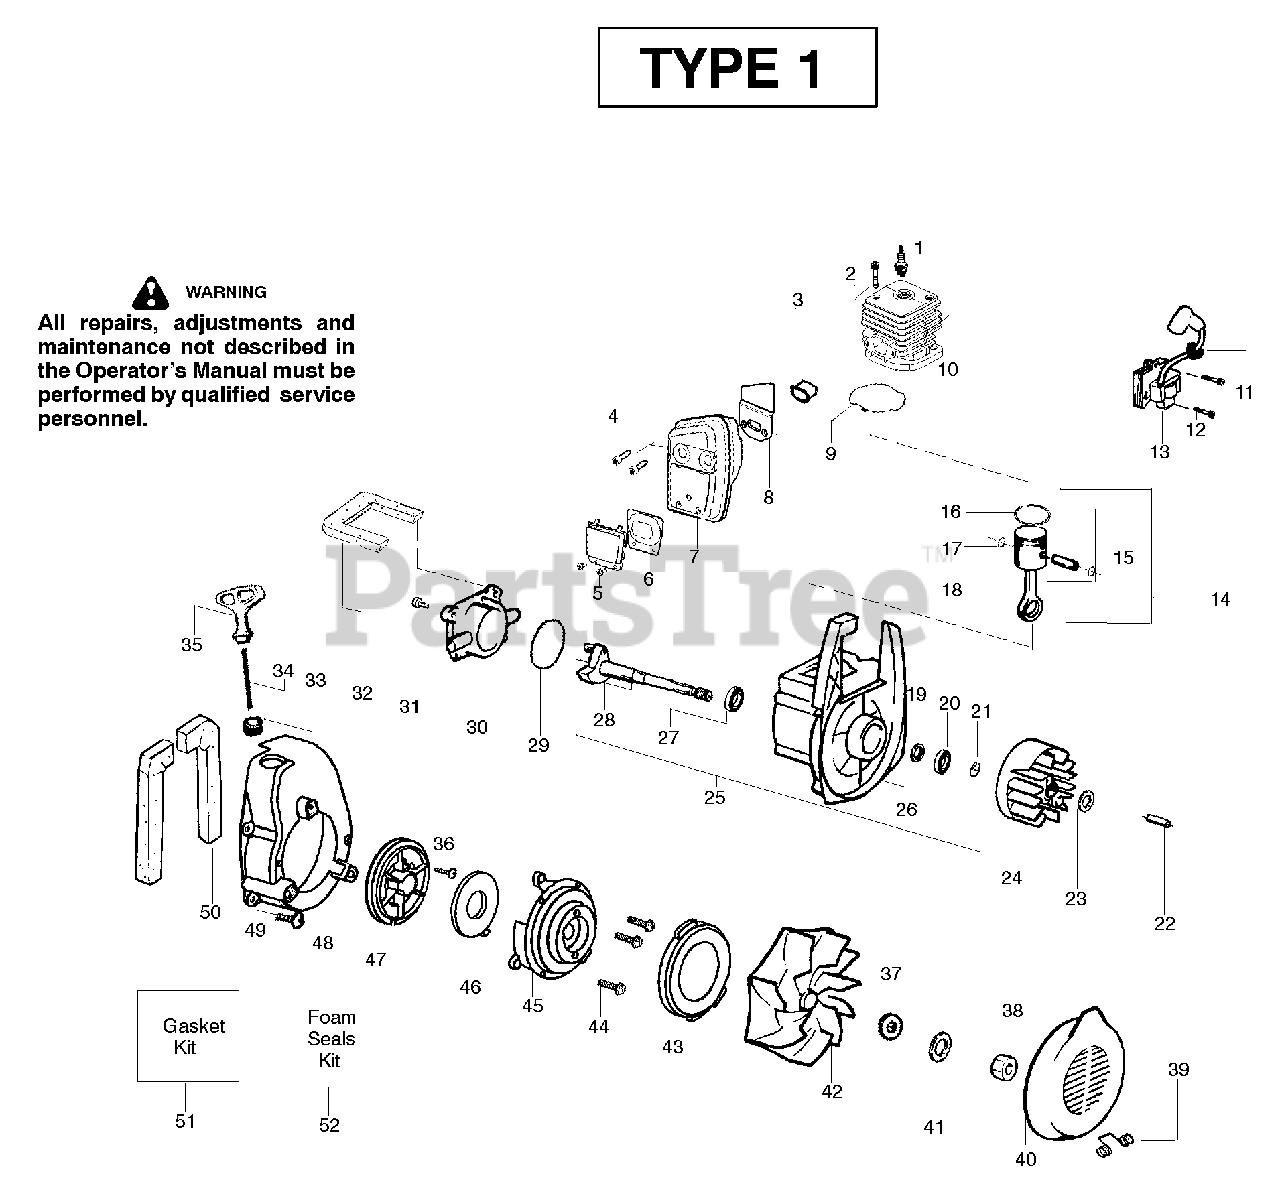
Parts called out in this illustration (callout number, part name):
1	Spark Plug (RCJ-6Y)
3	Insulator-Heat
4	Screw-Muffler-Internal
6	Kit-Spark Screen
7	Kit-Muffler
8	Gasket-Baffle (kit)
9	Gasket-Cylinder (kit)
11	Grommet-Ign. Module
12	Screw-Ignition Module
13	Ignition Module
14	Kit-Piston/Rod
15	Kit-Piston
16	Piston Ring
17	Retainer-Piston Pin
18	Assy-Connecting Rod
19	Seal-Crankcase
20	Bearing-Outer
21	Retainer Ring-C’chaft
22	Spacer-Flywheel
24	Assy-Flywheel
25	Assy-Crankcase/Crank shaft
26	Assy-Crankcase
27	Bearing-Inner
28	Assy-Crankshaft
29	O-ring-C/case (kit)
30	Cover-Crankcase
31	Screw
32	Foam-219mm (kit)
33	Eyelet-Flange
34	Kit-Rope
35	Handle-Starter
37	Washer-Belleville
39	Spring-Return Cover
42	Assy-Impeller
45	Housing-Pulley
46	Spring-Starter
47	Kit-Starter Pulley
49	Screw
50	Foam-182mm (kit)
51	Kit-Gasket
52	Kit-Foam Seals
